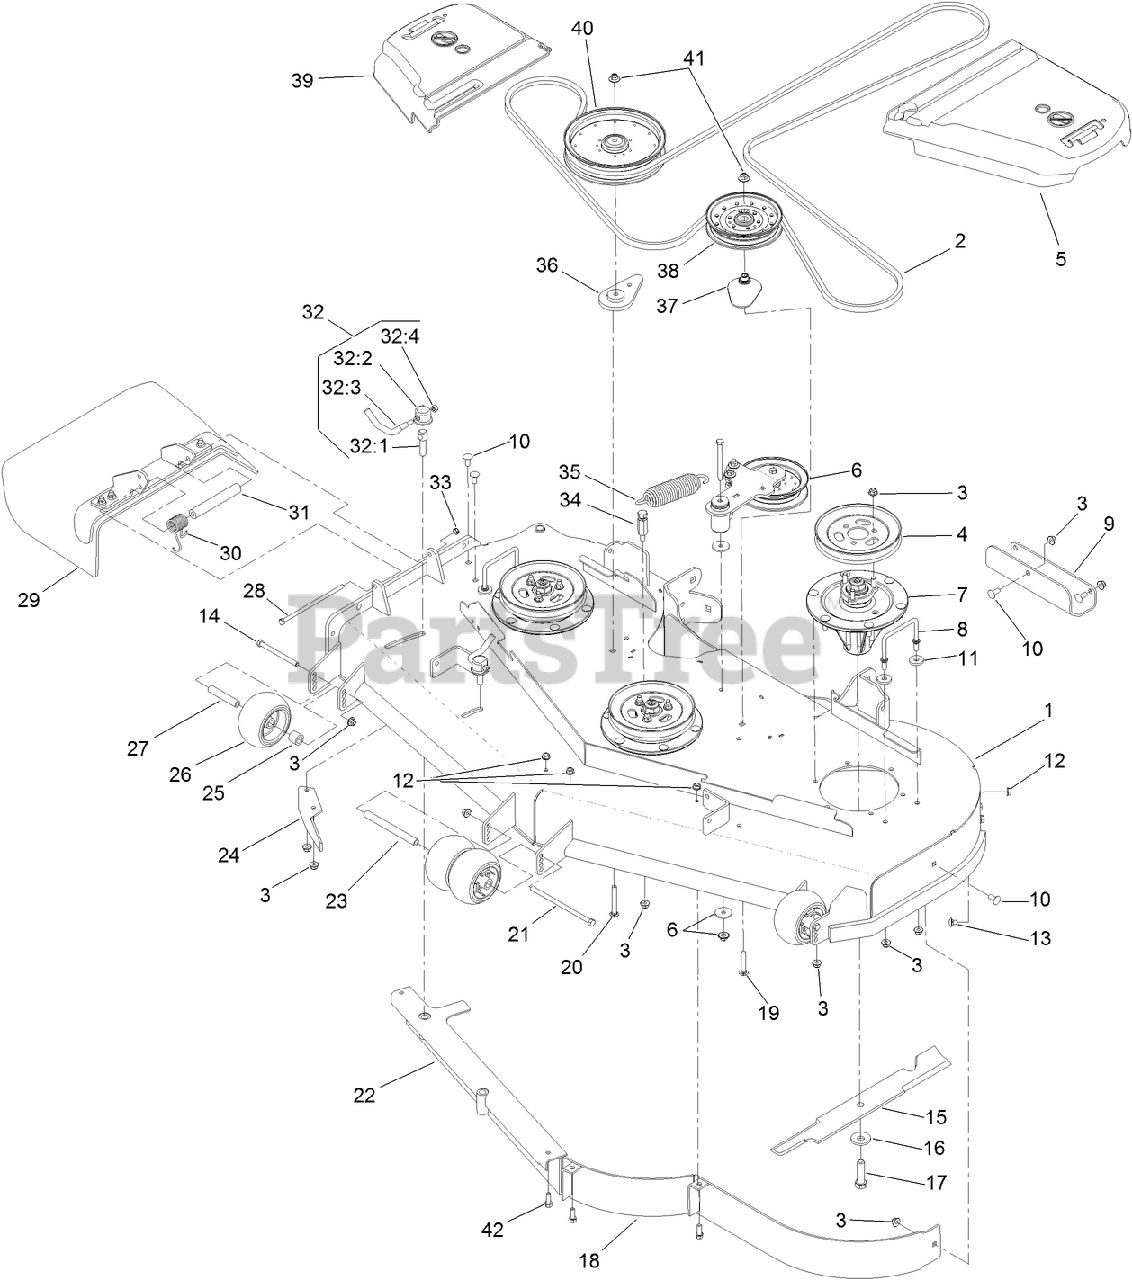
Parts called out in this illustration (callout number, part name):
1	DECK DECAL ASM
2	BELT-V
3	NUT-HF, NI
4	Pulley
5	COVER-BELT, LH
6	IDLER ARM ASM
7	SPINDLE ASM
8	WIREFORM-COVER
9	PLATE-SKID
10	SCREW-CARR
11	WASHER
12	NUT-HHF, WHIZ
13	SCREW-CARR
14	SCREW-HH
15	BLADE-HI FLOW
16	Washer-Blade Bolt, Heavy
17	SCREW-BLADE
19	BOLT-CARR, SHORT NECK
20	SCREW-CARR
21	SCREW-HH
23	SPACER-WHEEL
24	BAFFLE-DISCHARGE
25	TUBE-SPACER
26	ROLLER-SCALP, ANTI
27	TUBE-SPANNER
28	SCREW-HH
29	RUBBER DEFLECTOR ASM
30	SPRING-TORSION
31	SPACER
32	LEVER ASM
32:1	Screw-Lock
32:2	CAP-LOCK
32:3	Lever-Lock
32:4	NUT-LOCK, NI
33	NUT-LOCK, NI
34	ANCHOR-SPRING, TALL
35	SPRING-EXTENSION
36	SPACER-IDLER
37	SPACER-PULLEY
38	PULLEY-IDLER, FLAT
39	COVER-BELT, RH
40	PULLEY-IDLER
41	NUT-FLANGE, NI
42	SCREW-HWH
